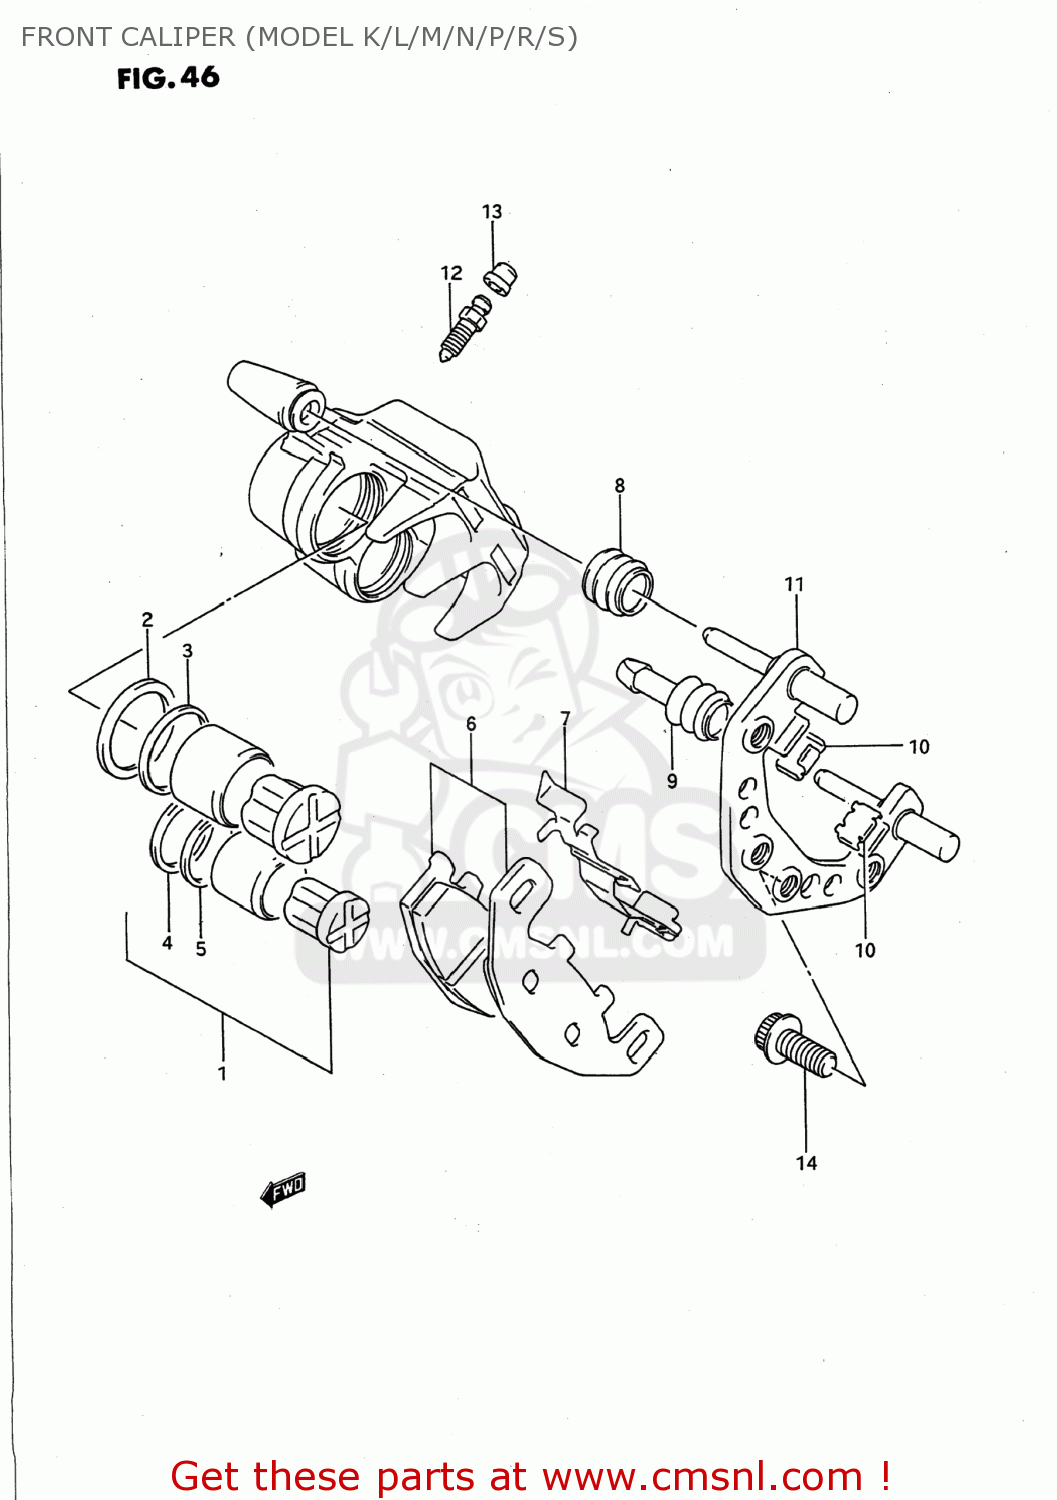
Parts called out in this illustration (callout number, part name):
1	PISTON SET
2	SEAL,PISTON
3	SEAL,WIPER
4	SEAL,PISTON
5	SEAL,WIPER
6	PAD SET (NAS)
7	SPRING,PAD
8	BOOT,AXLE
9	INSULATOR,AXLE
10	GUIDE,PAD
11	CARRIER,CALIPER
12	BLEEDER
13	CAP,BREATHER
14	BOLT
